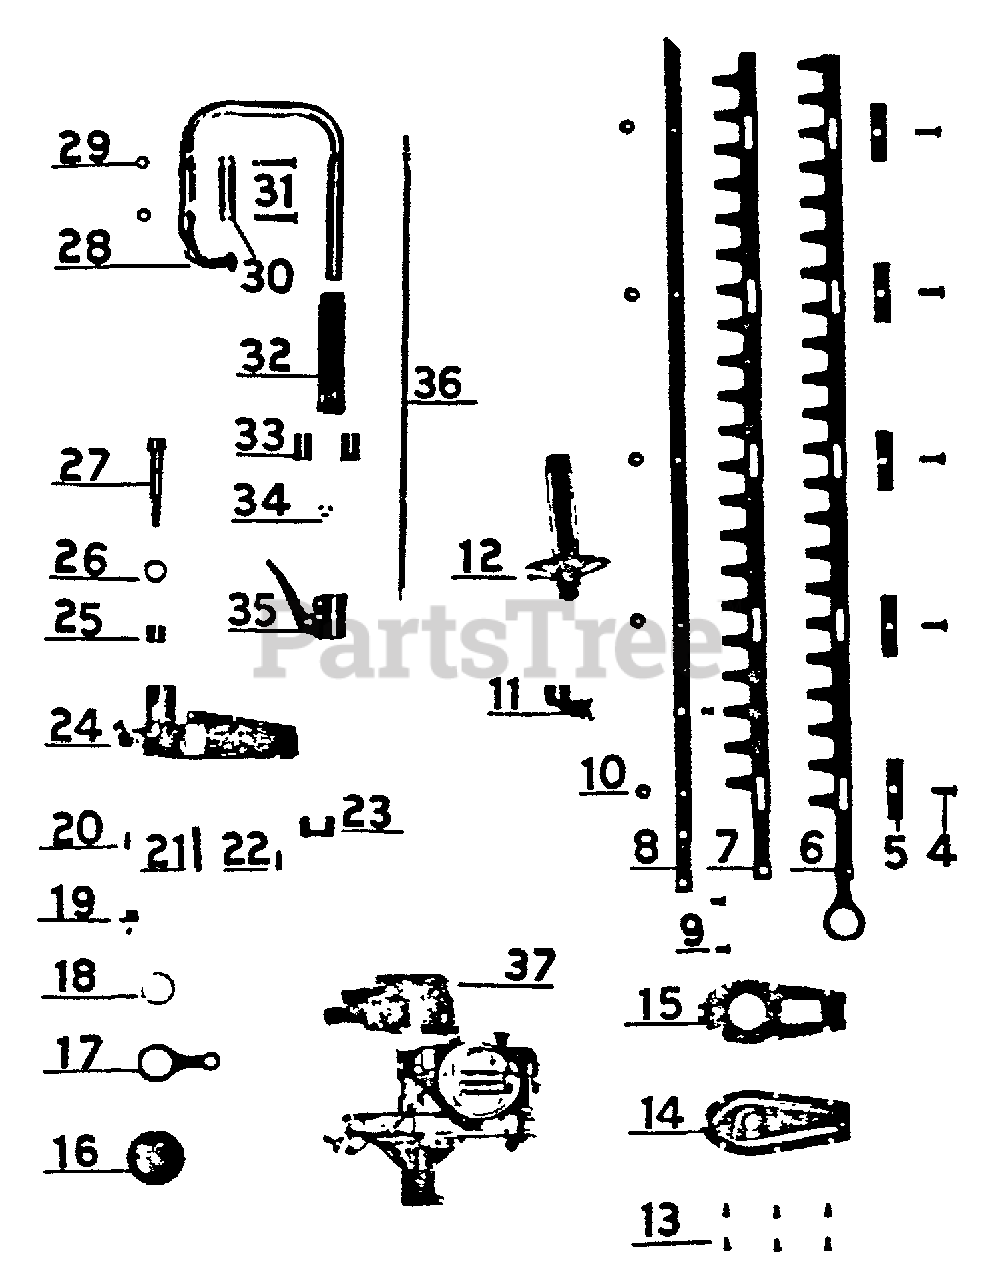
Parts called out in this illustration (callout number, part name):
4	SCREW
5	GUARD, BLADE
6	BLADE - OUTER -- 30"
7	BLADE - INNER -- 30"
8	STIFFENER, BLADE
9	SCREW, FLAT
10	NUT, FLANGE
11	HANDLE ADAPTER
12	PLASTIC HANDLE
13	SCREW
14	COVER, GEAR CASE
15	GASKET
16	ECCENTRIC GEAR
17	CONROD
18	CONROD
19	BUSHING - LOWER
20	PIN, COVER PLATE
21	SHAFT, ECCENTRIC
22	WEAR STRIP
23	SEAL, FELT
24	CASE, GEAR
25	BUSHING - UPPER
26	WASHER - 1/2"
27	PINION
28	WASHER - 1/2"
28	HANDLE - REAR
29	NUT - 1/4"-20×1-1/2"
30	CLAMP, HANDLE
31	BOLT - 1/4-20×1-1/2"
32	GRIP
33	RETAINER, CABLE
34	RING, RETAINING
35	LEVER, THROTTLE
36	CABLE, THROTTLE
37	KIORITZ ENGINE
